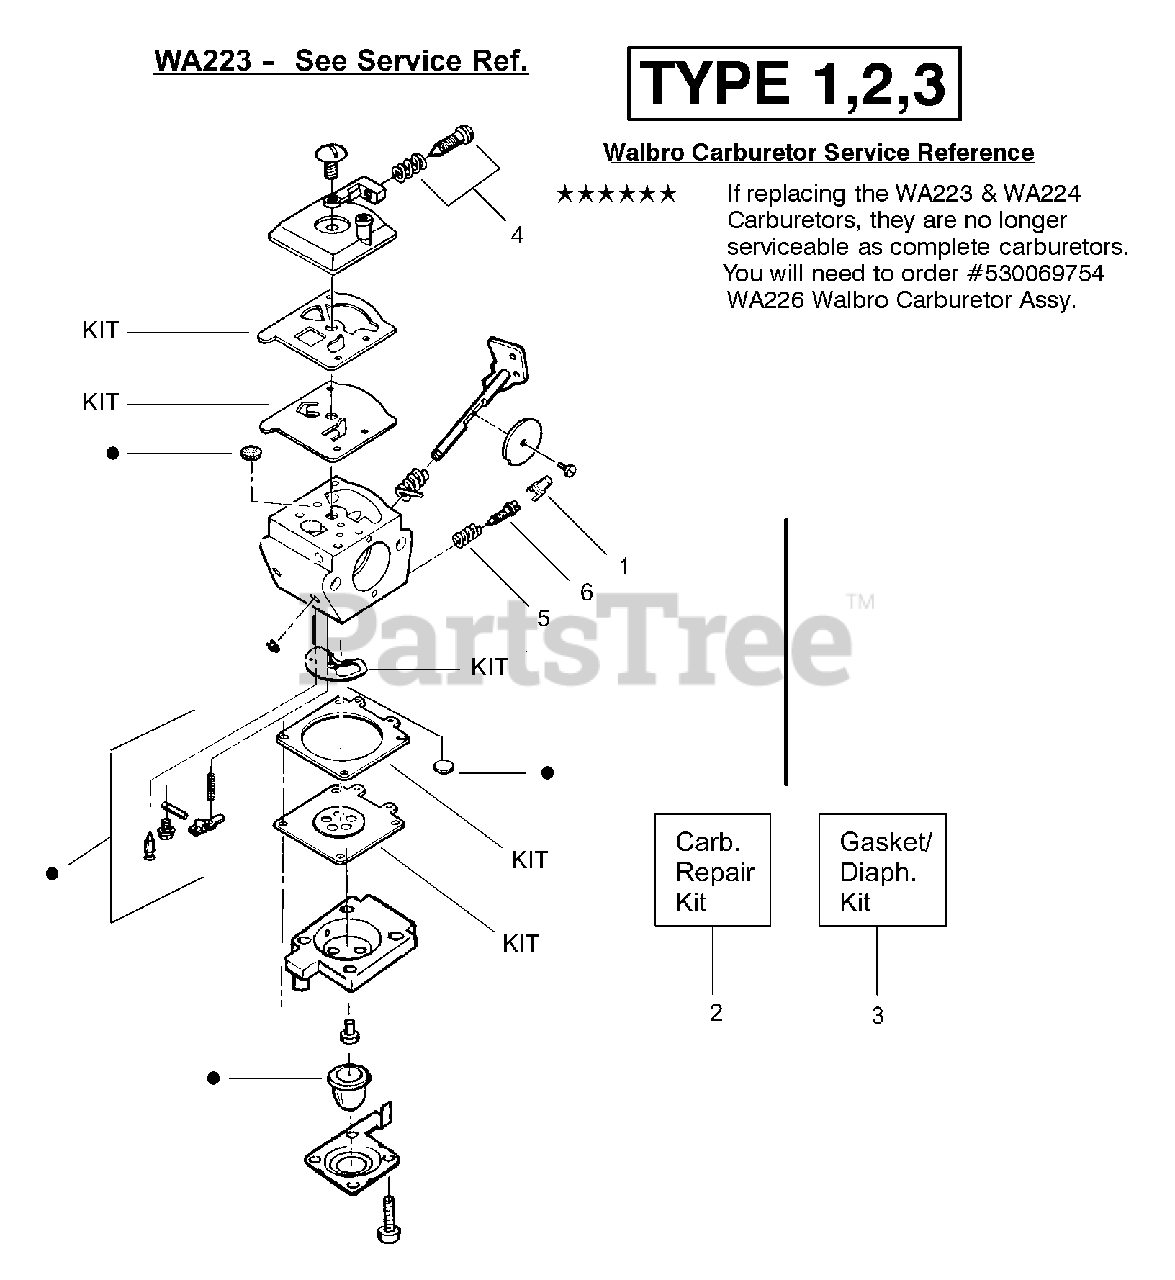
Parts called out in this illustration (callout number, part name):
1	Limiter Cap
2	Carburetor Repair Kit WA223
3	Gasket/Diaphragm WA223, WA224 & WA226
4	Idle Screw & Spring Kit
5	Low Speed Spring
6	Low Speed Needle
